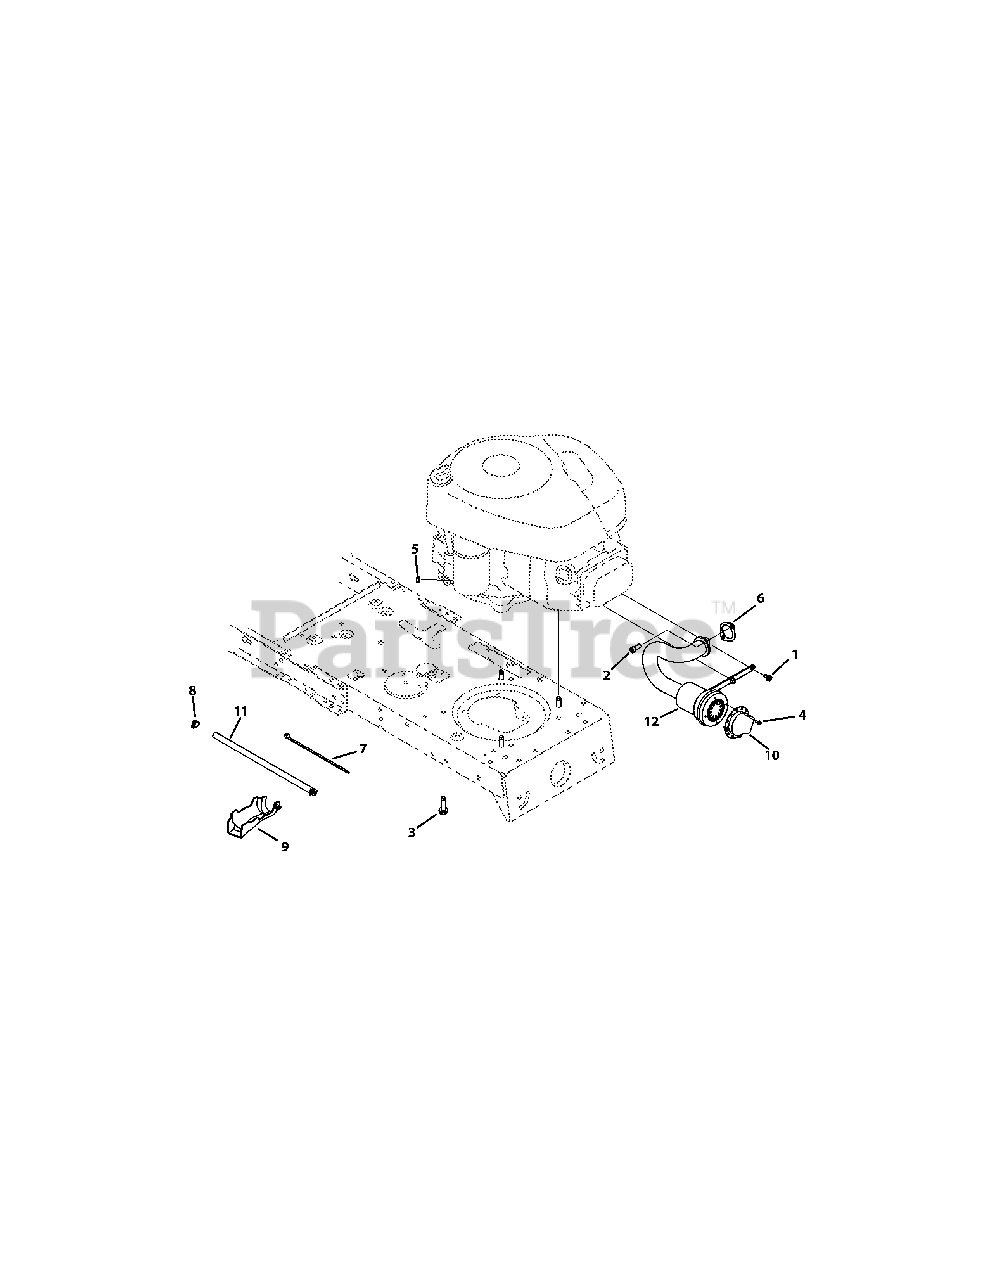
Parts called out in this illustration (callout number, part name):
1	Screw, 1/4-20 x .500
2	Socket Screw, 5/16-18 x .750
3	Screw, 3/8-16 x 1.0
4	Screw, 8-18 x .500
5	Sems Nut, 1/4-20
6	Exhaust Gasket, 10 HP Briggs
7	Cable Tie
8	Clamp Hose, .490 diameter
9	Oil Drain Sleeve
10	Muffler Deflector
11	Fuel Hose, Low Permeation
12	Muffler
